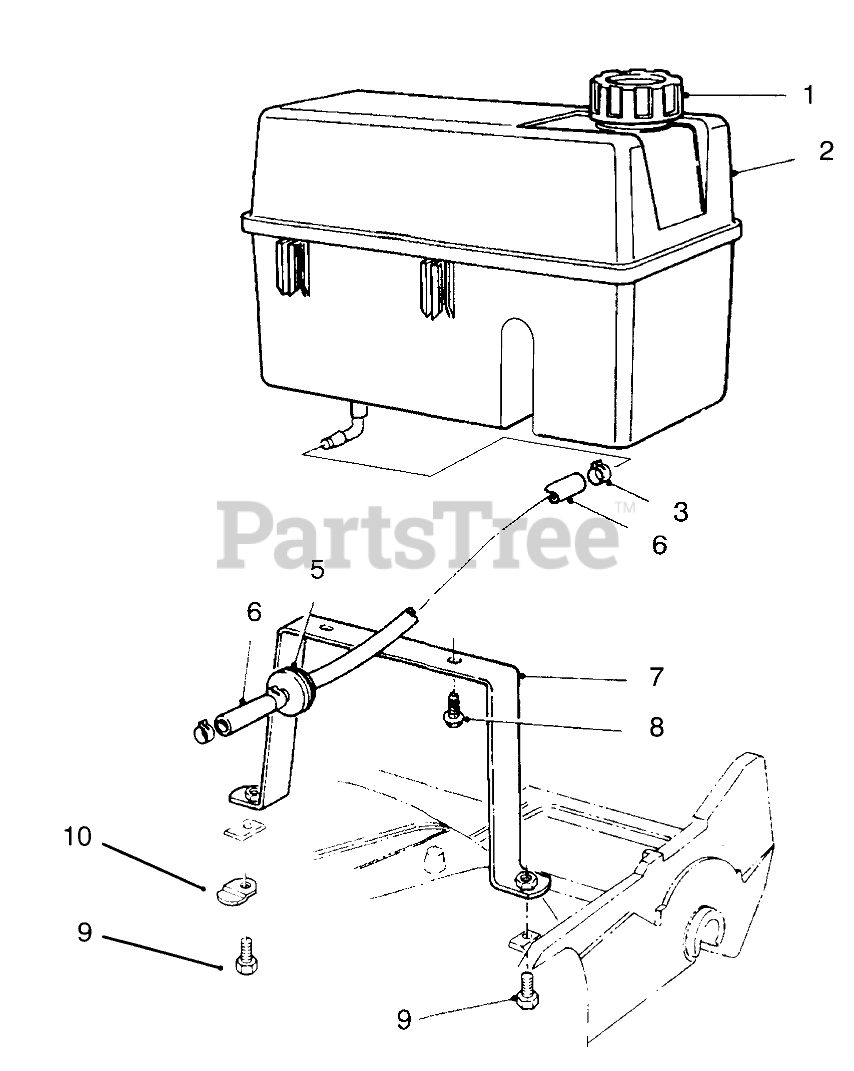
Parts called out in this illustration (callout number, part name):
1	GAS CAP ASM
2	TANK - FUEL
3	CLAMP-FUEL LINE
5	FILTER-FUEL
6	HOSE-FUEL
7	Wa-Base
8	SCREW-HWH
9	SCREW-HH
10	SHIELD-RETAINER
